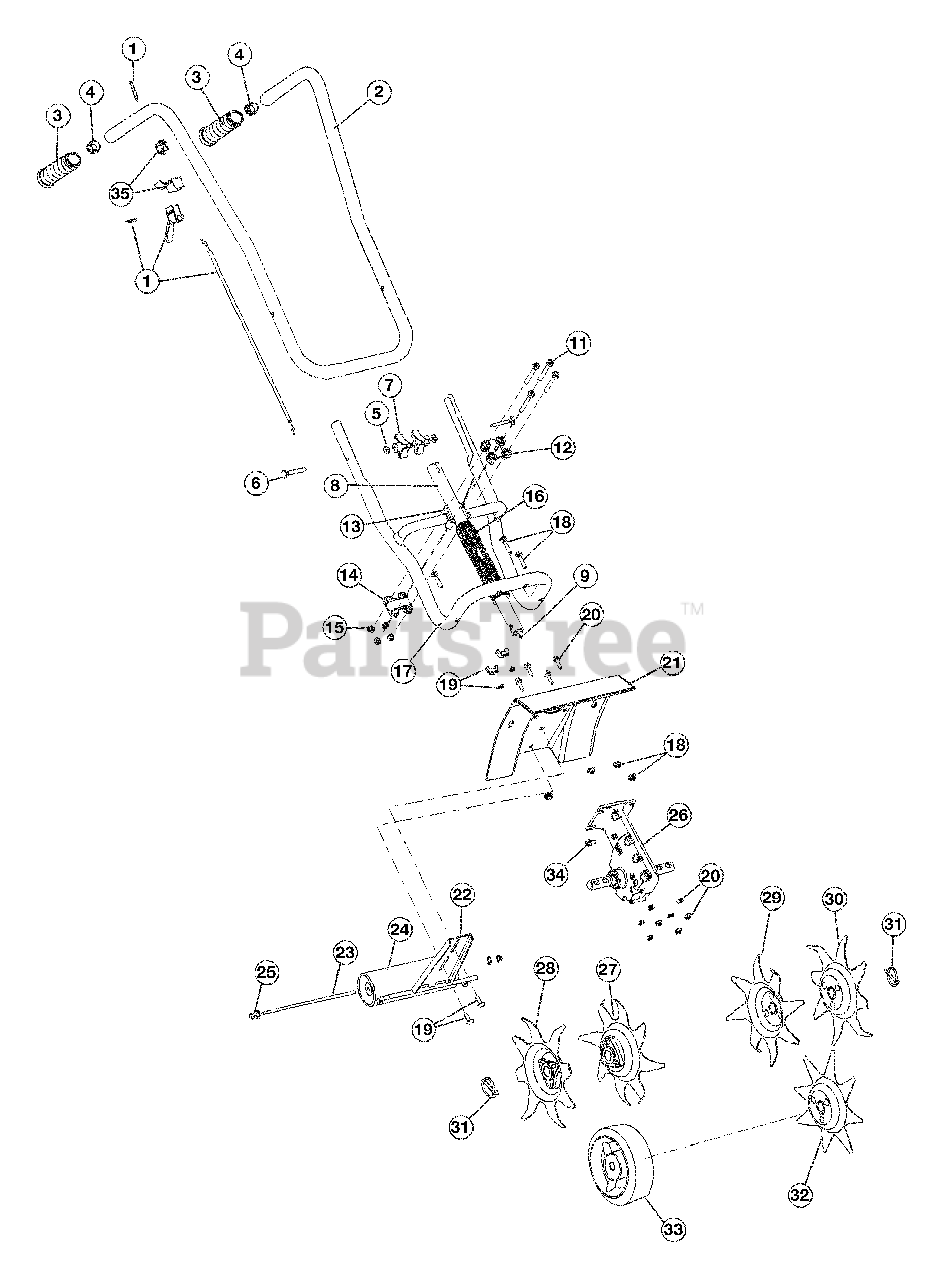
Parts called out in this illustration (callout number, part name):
1	Throttle Trigger and Cable Assembly
2	Handle Bar Assembliy, Upper
4	Tube Closure
5	Washer
7	Knob, 3 prong
8	Drive Shaft Housing Assembly
9	Flexible Drive Shaft
10	Handle Bracket Assembly
12	Upper Handle Clamp
13	Middle Handle Clamp
14	Lower Handle Clamp
17	Lower Handle Bar
18	Hardware, Handle Bar Mounting (lower)
19	Wheel Bracket Mounting Hardware
20	Guard Mounting Hardware
22	Roller Bracket Assembly
23	Roller Axle
24	Roller
25	Roller Cap
26	Gearbox Assembly
27	Inner Tine (right side)
28	Outer Tine (right side)
29	Inner Tine (left side)
30	Outer Tine (left side)
31	Click Pin
32	Edger Tine
33	Edger Wheel
34	Sleeve Retainer Bolt
